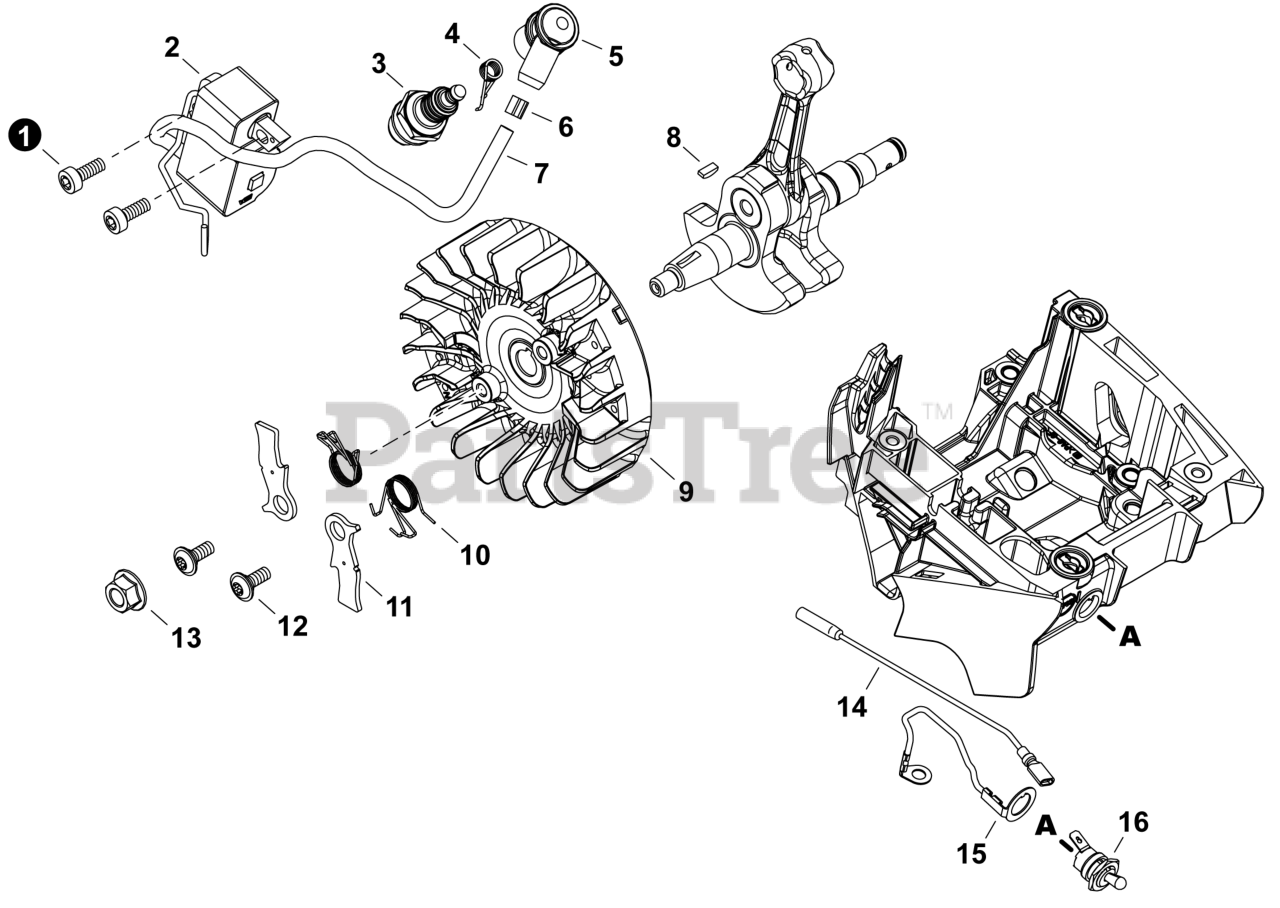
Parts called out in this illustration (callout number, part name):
1	BOLT, TORX 5x16
2	COIL, IGNITION
3	SPARK PLUG - BPMR8Y-5
4	TERMINAL, SPARK PLUG
5	CAP, SPARK PLUG
7	TUBE, INSULATOR
8	KEY, WOODRUFF
9	FLYWHEEL
10	SPRING, TORSION
13	NUT, FLANGE M8
16	SWITCH, ON-OFF
